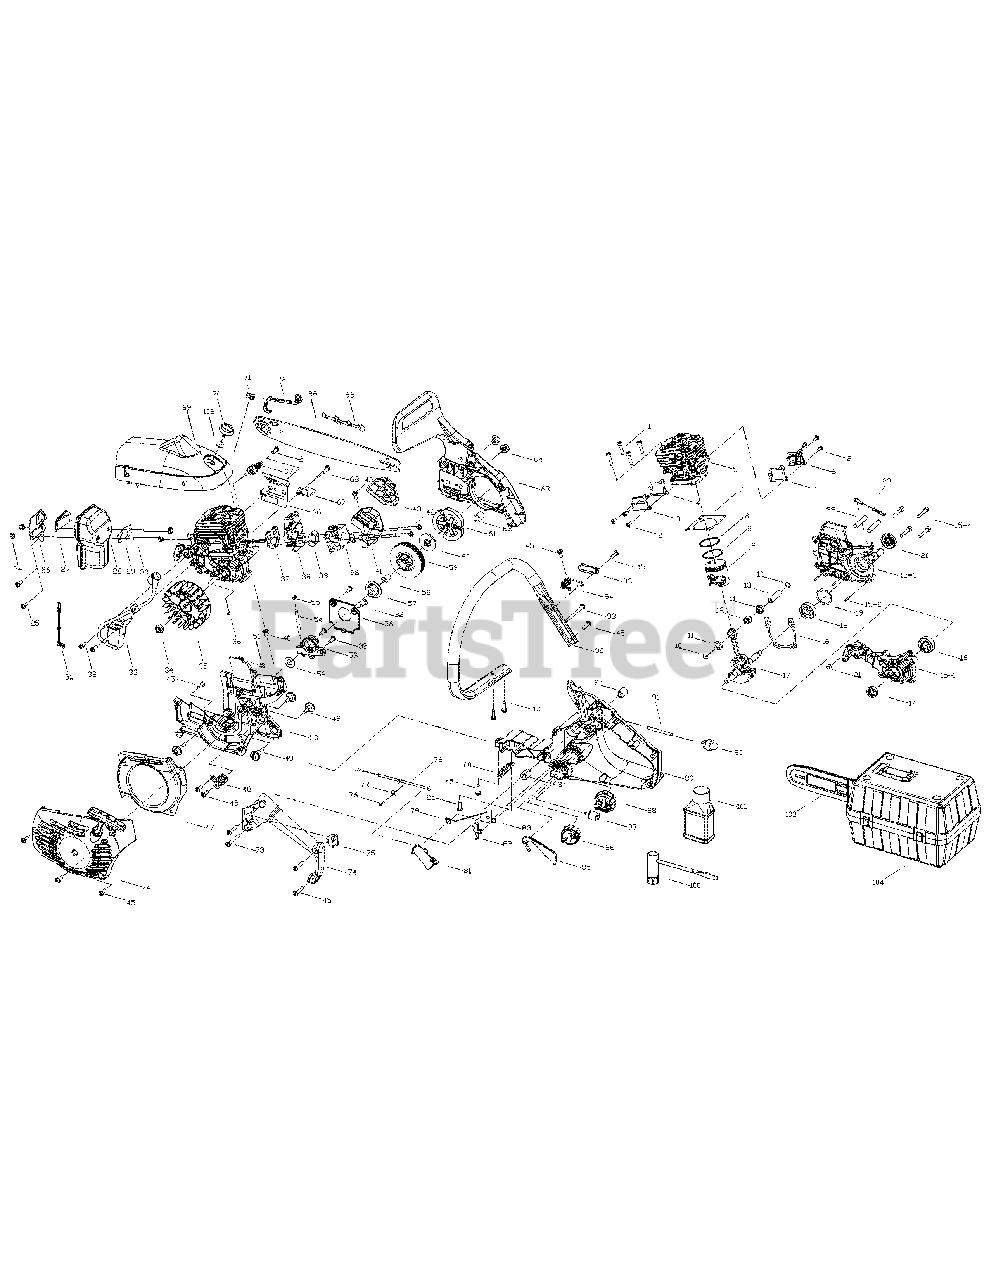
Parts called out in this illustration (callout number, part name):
1	SCREW
3	CAP
5	CYLINDER
6	CAP
8	PISTON RING
13	PIN, PISTON
14	SEAL
15	CLY CASE ASS'Y
15-1	CLY CASE, LEFT
15-3	CLY CASE, RIGHT
16	BEARING
17	CRANK/ROD ASS'Y
19	RING
22	SCREW
25	SCREW
26	COVER, MESH
27	SPARK ARRESTER
28	MUFFLER ASS'Y
29	BAFFLE
30	SCREW
32	SCREW
33	IGNITION ASS'Y
35	FLYWHEEL ASS'Y
36	WOODRUFF KEY
37	SPACER
38	ISOLATER, CARBURETER
40	RUBBER PLUG
41	AIR GUIDE ASS'Y
45	SCREW
46	STARTER HOUSING ASS'Y
47	CAP, AIRWAY
50	BRACKET
53	PUMP ASS'Y
55	CONNECTOR
56	CAP, ANTI-DUST
57	WORM
59	DRUM ASS'Y
60	WASHER
61	CLUTCH ASS'Y
62	RUBBER PLUG
63	BRAKE KIT ASS'Y
64	NUT
65	SPACER
66	CHAIN CATCH
71	HOLDER, CHOKE LEVER
72	LEVER, CHOKE
73	SCREW
74	HANDLE ASS'Y (L)
76	SCREW
78	CABLE, THROTTLE
80	SPRING
81	TRIGGER, THROTTLE
82	TRIGGER, THROTTLE
84	RUBBER PLUG
85	TRIGGER,RELEASE
86	OIL CAP ASS'Y
87	FUEL FILTER
88	FUEL CAP ASS'Y
89	HANDLE ASS'Y (R)
92	HANDLE, FRONT
95	CAP, SPRING
96	CARBURETER WT-808A
97	SPARK PLUG CHAMPION R27C
99	16" CHAIN
99	18" CHAIN
100	SPANNER
103	SCABBARD
104	CARRY CASE
